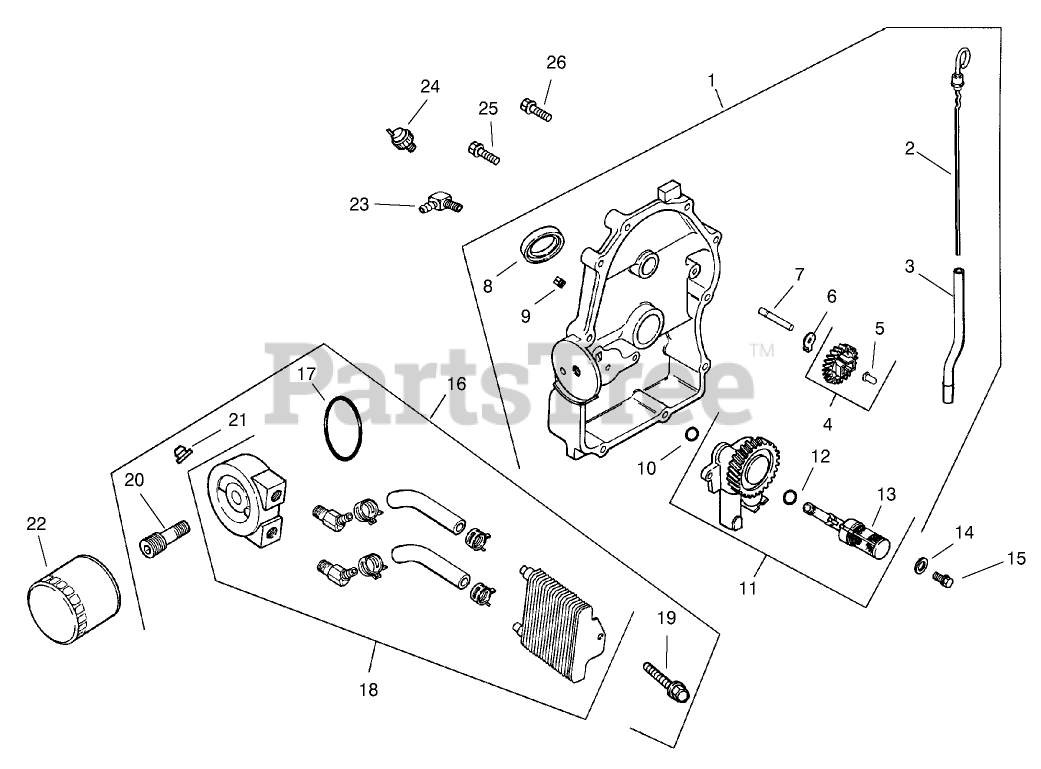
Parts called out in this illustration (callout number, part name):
1	Closure Plate ASM (Incl. Ref. #2-12)
2	Dipstick
3	Tube-Dipstick
4	Kit-Gear, Governor (Incl. Ref. #5)
5	Pin-Governor
6	Tab-Locking
7	Shaft-Gear, Governor
8	Seal-Oil
9	Plug
10	O Ring
11	Oil Pump ASM(Incl. Ref. #12, 13)
12	O-Ring
13	Pick Up-Oil
14	Washer
15	Screw
16	Kit-Cooler, Oil (Incl. Ref. #17-21)
17	O-Ring
18	Cooler-Oil
19	Screw
20	Nipple, oil filter
21	Nut
22	Filter-Oil
23	Connector
24	Switch-Pressure
25	Screw
26	Screw
